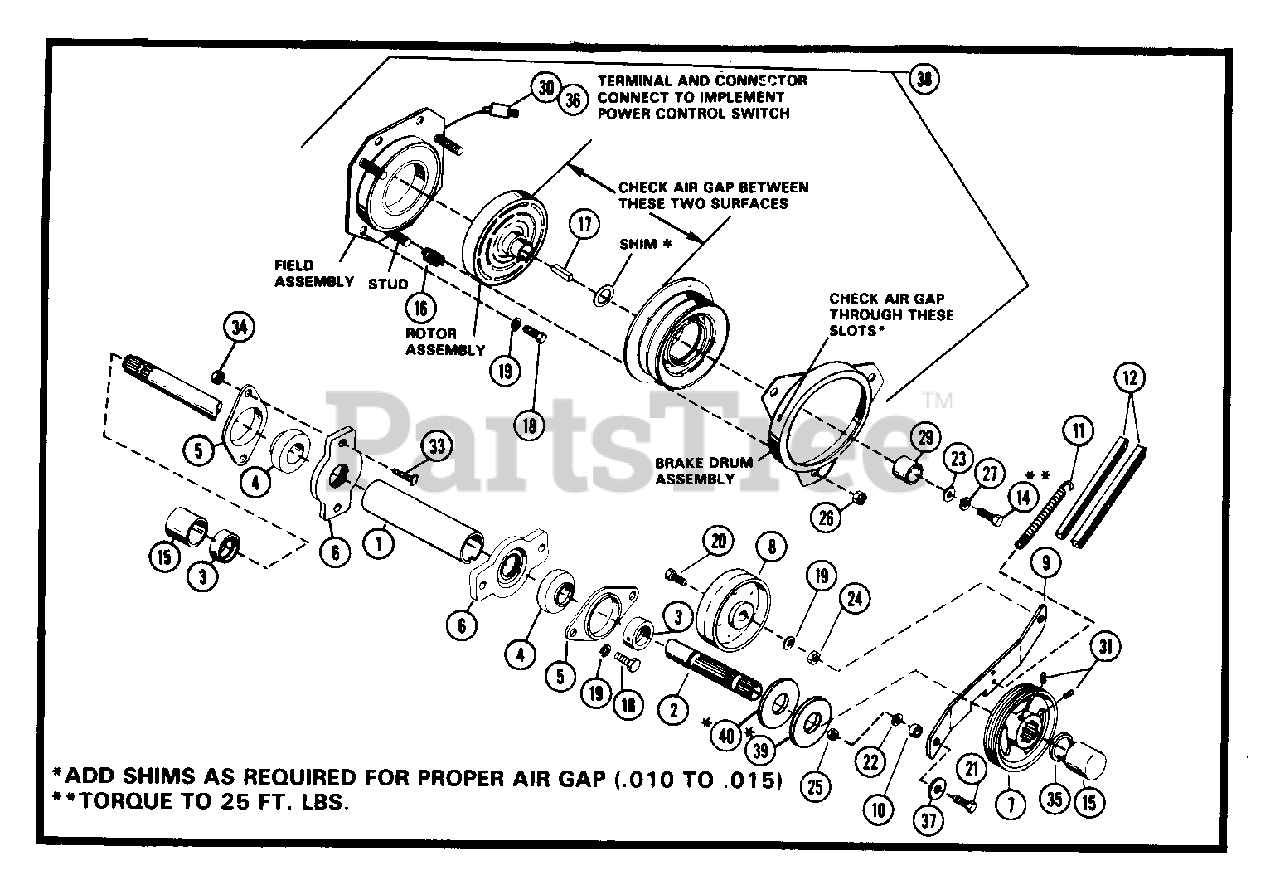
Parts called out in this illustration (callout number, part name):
1	P.T.O. TUBE
2	FRONT P.T.O. SHAFT
3	BEARING COLLAR
4	BRG/W COLLAR 1.0 X 2.047 X.844
6	BEARING MOUNTING FLANGE
7	SHEAVE
8	IDLER-FLAT 3.218X.38
9	IDLER ARM
10	SPACER .512X.747X.208
11	SG-TENS 6.0 FREE LENGTH
12	V-BELT, 4L-WRAPPED (SET)
14	BLT-HEX .44-20X1.50 PL GR5
15	SHAFT COVER
16	SG-COMP WARNER ELEC.
17	KEY-SQ .25X.625X.25 SAE 8630
18	BLT-HEX .38-16X1.50 PL GR2
19	WSHR-LK .375X.094 MED PL
20	BLT-HEX .38-16X2.00 PL GR2
21	BLT-HEX .50-13X1.25 PL GR2
22	SHIM SPACER
23	WSHR-FL-STL .515X1.625X.250
24	NUT-HEX .375-16
25	NUT-LK .50-13 PL
26	NUT-LK WARNER
27	WSHR-LK .438X.133 HVY
29	SPACER 1.129X1.375X.855
30	MALE TERMINAL
31	SCR-SET .32-18X.38 SKHCUPNL OH
33	BLT-RDHDSQNK .38-16X1.50 PL
34	NUT-LK-CTR .375-16 GR A PL
35	RG-RTNG-EXT 1.00X.042
36	CONNECTOR BODY
37	WSHR-FL-STL .518X2.000X.105
38	CLUTCH ASSEMBLY - 1-1/4 BORE
38	CLUTCH ASSEMBLY 1-1/8 BORE
39	WSHR-FL-STL 1.015X1.500X.125
40	WSHR-FL-STL 1.016X1.625X.045
